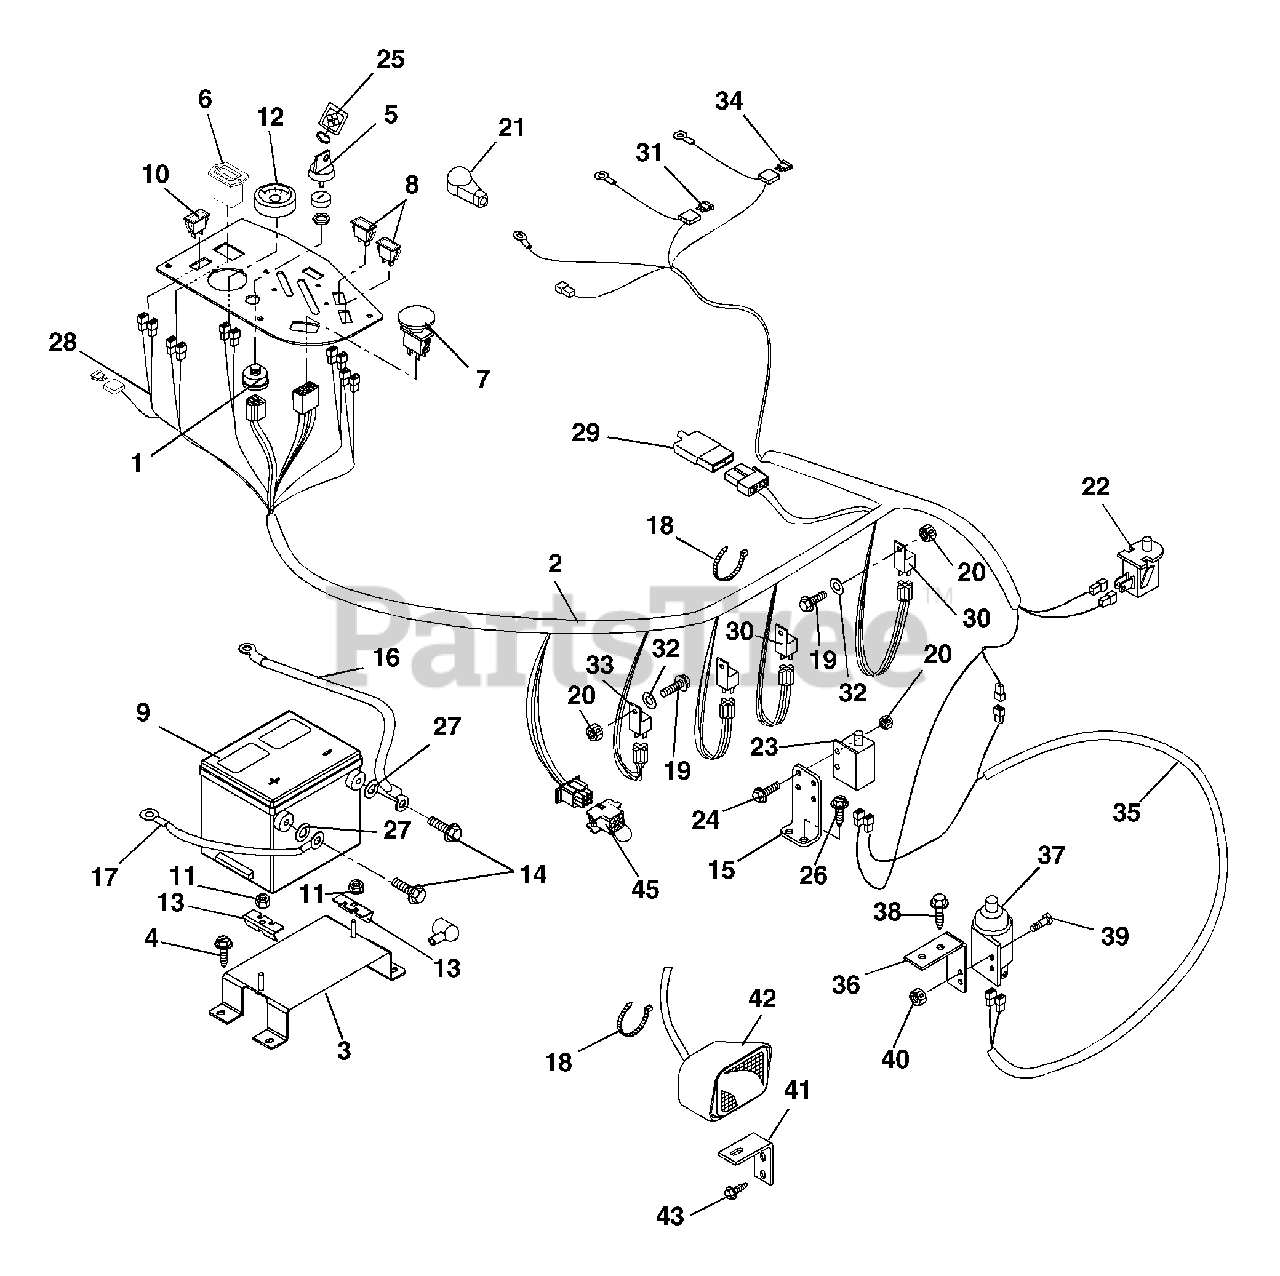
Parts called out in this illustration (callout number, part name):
1	SWITCH, IGNITION (DIESEL)
2	HARNESS, DIESEL-L/C (EYE-Q)
3	WMT, BATTERY SUPPORT
4	@SCR-TAP .38-16X.75 HWH TR YWZ
5	KEY, W/ SHIELD
6	HOUR METER, QUARTZ
7	SWITCH, CLUTCH
8	LIGHT,INDICATOR
9	BATTERY, GROUP 70 450 CCA 35 A
10	SWITCH, 2 POLE/ROCKER
11	@NUT-LK-TOP-FLG .31-18 YWZC
12	GAUGE, TEMPERATURE
13	BRKT, BATTERY HOLD-DOWN
14	BATT TERMINAL SCREW
15	MOUNT, SAFETY SWITCH
16	CABLE, POS BATT 4 GA X 45
17	CABLE, NEGATIVE BATTERY 49.00
18	CABLE TIE LG 5-1/2
19	@SCR-MCH 10-24X.75 HWH YWZC
20	@NUT-LK-NYL 10-24 W/INSRT YWZC
21	BOOT, BATTERY TERMINAL-RED
22	SWITCH- SNAP MTG N.O.
23	SWITCH- SINGLE POLE N.O.
24	@SCR-MCH 10-24X.75 HWH YWZC
25	KEY CHAIN
26	@SCR-TAP .25-20X.50 HWH TR YWZ
27	WSHR-FL-STL .406X1.00X.188 YWZ
28	FUSE, 15 AMP.
29	DIODE, CONNECTOR SHELL
30	RELAY
31	FUSE, 30 AMP.
32	@WSHR-FL-STL.250X.56X.049 YWZC
33	Pre-Heat Timer
34	FUSE, 50 AMP (MAXI FUSE)
35	HARNESS, WIRE ADAPTER CE
36	MOUNT - SWITCH
37	SWITCH-SINGLE POLE N.O.W/COVER
38	@SCR-TAP .31-18X.50 HWH TR YWZ
39	@SCR-MCH 10-24X.75 HWH YWZC
40	@NUT-LK-NYL 10-24 W/INSRT YWZC
41	BRACKET, HEADLIGHT MTG
42	HEADLIGHT
43	@SCR-TAP .38-16X.50 HWH TR YWZ
44	BOOT, EYELET TERMINAL
45	HARNESS - EYE-Q
